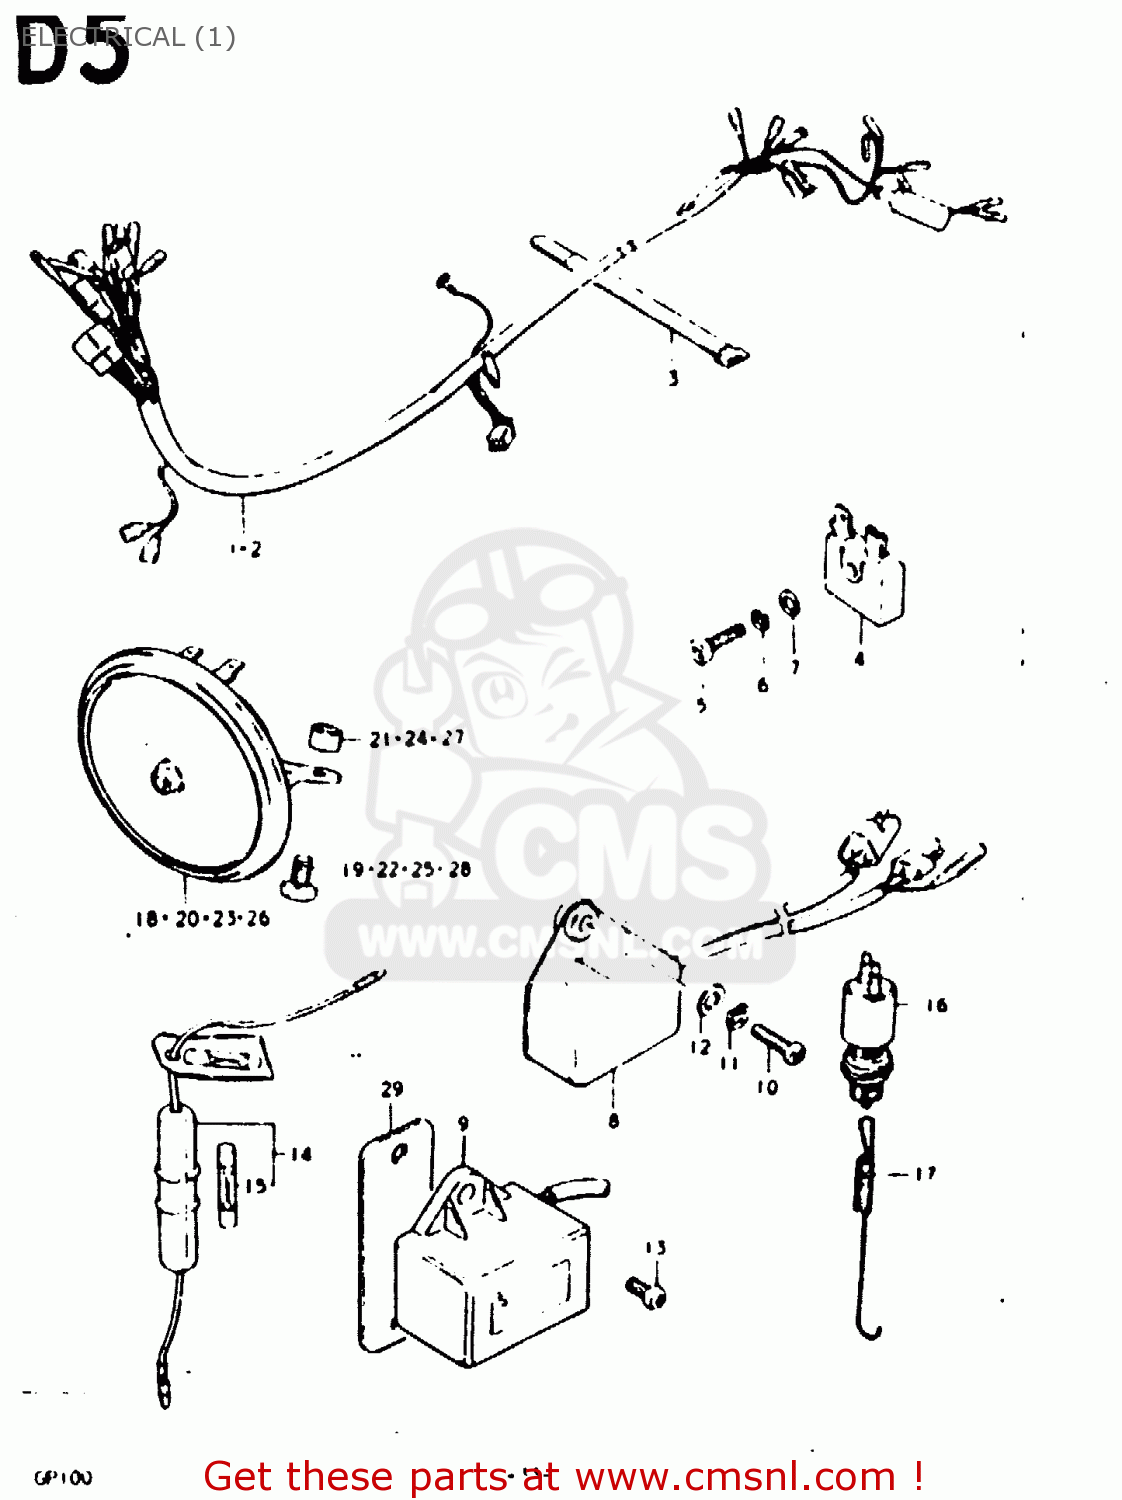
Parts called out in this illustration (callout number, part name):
2	WIRING HARNESS
3	CLAMP
4	RECTIFIER ASSEMBLY
5	SCREW
8	C.D.I UNIT ASSY
10	SCREW
11	LOCK WASHER
12	WASHER
14	BOX ASSEMBLY,FUSE
15	FUSE(10A)
16	SWITCH ASSY,BRAKE LAMP
17	SPRING
18	HORN ASSY
19	BOLT
